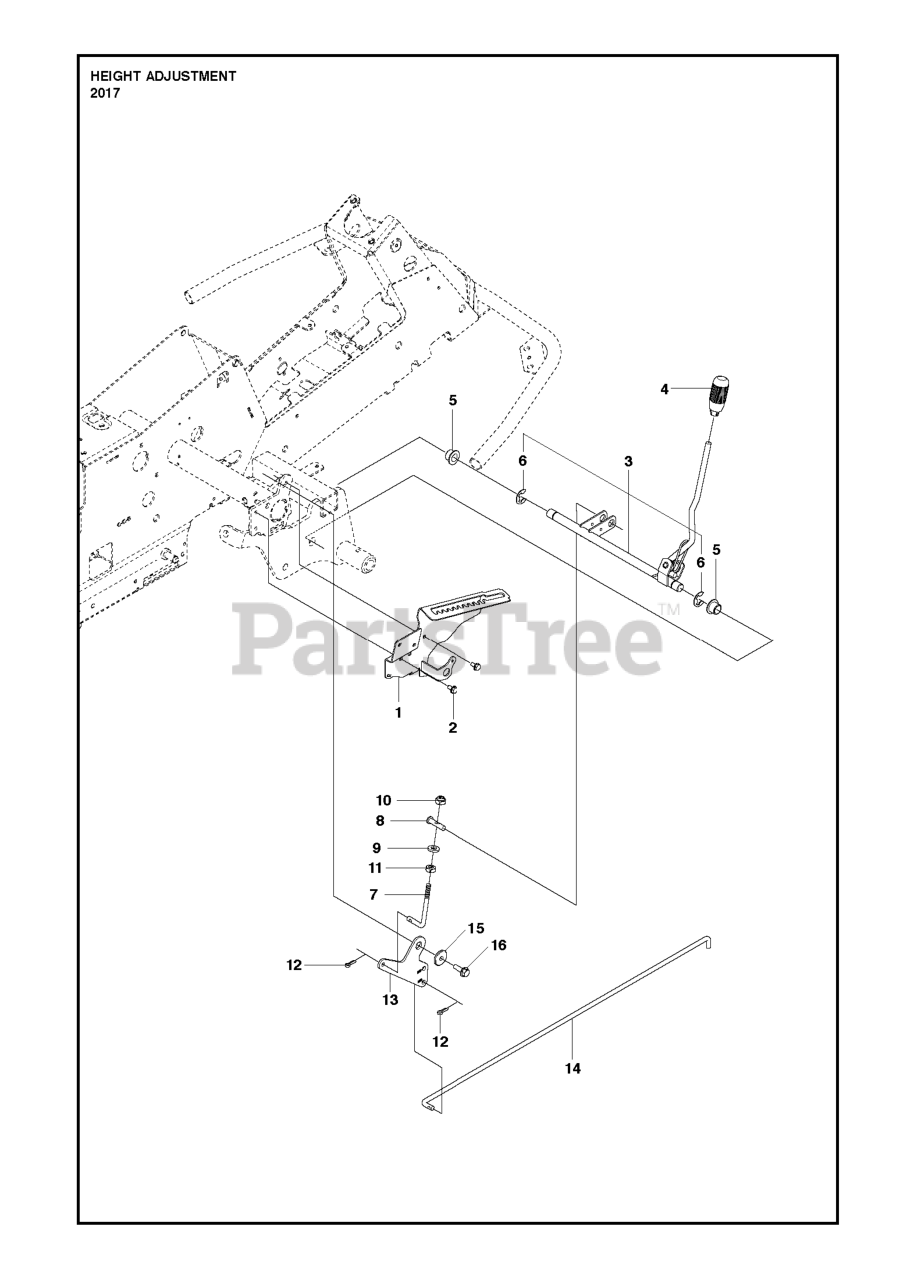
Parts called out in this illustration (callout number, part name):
1	BRACKET ASSY
3	HEIGHT ADJUSTER
4	GEAR STICK KNOB
5	BEARING FLANGE
9	WASHER
10	LOCKNUT M8
11	NUT
14	CONNECTION ROD
15	WASHER
15	WASHER PLASTIC ASSY
16	BOLT
